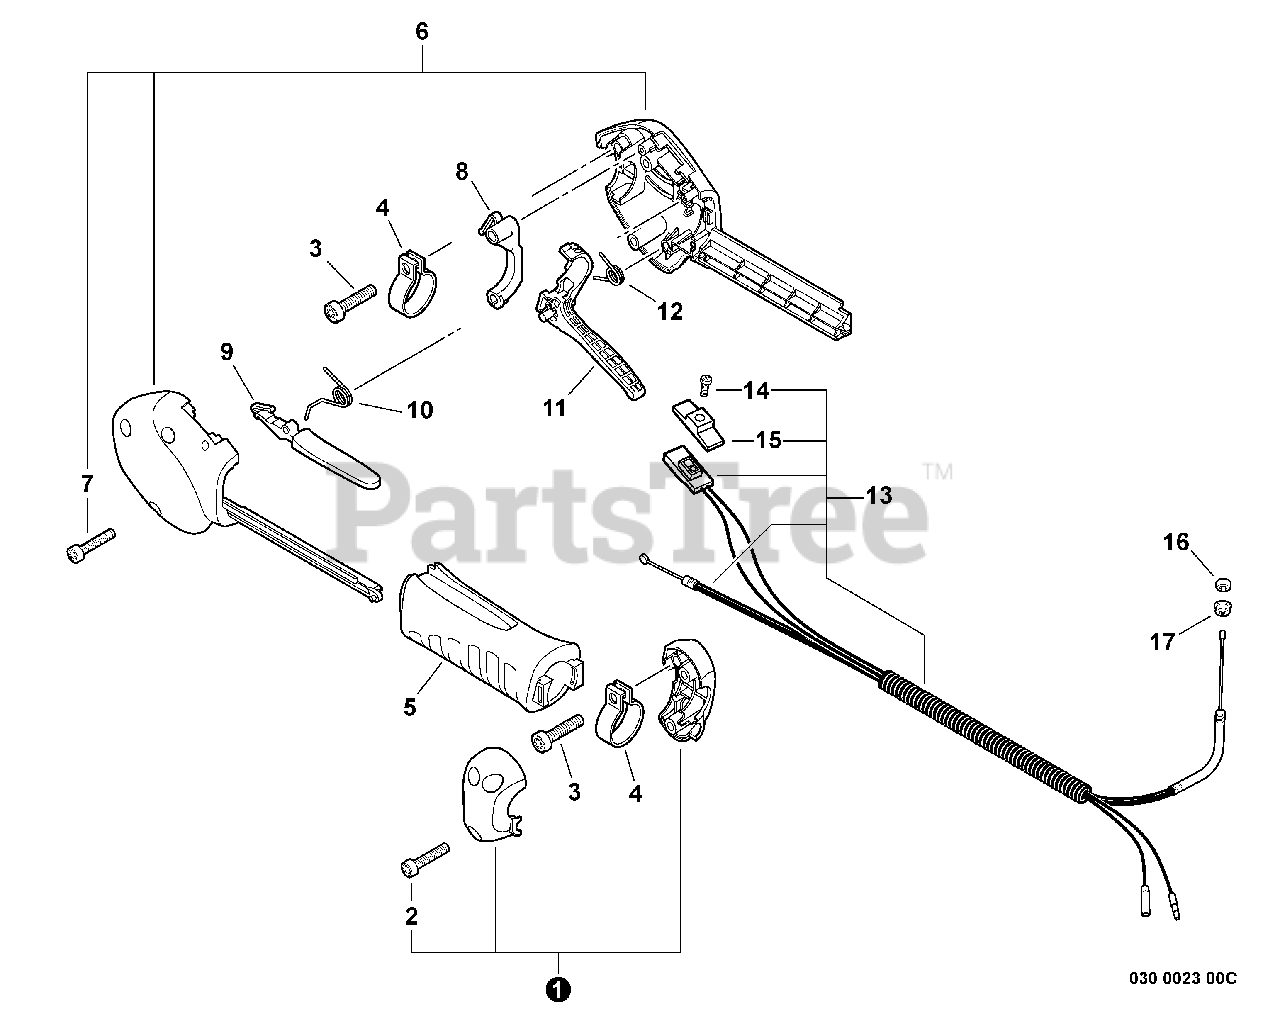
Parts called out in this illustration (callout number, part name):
1	GASKET KIT: ENGINE, INTAKE, EXHAUST
2	GASKET, CRANKCASE
3	GASKET, CYLINDER
4	GASKET, INTAKE
5	HEAT SHIELD, INTAKE
6	HEAT SHIELD, EXHAUST
7	GASKET, EXHAUST
8	FUEL SYSTEM KIT
9	VENT ASSY
10	FILTER, FUEL
11	GROMMET, FUEL Ø5
12	CONNECTOR, PIPE Ø5ר3.5
13	PIPE, FUEL 3×5×110 BLACK
14	PIPE, FUEL 3×6×80 CLEAR
15	PIPE, FUEL 3×5×74 BLACK
16	PIPE, FUEL 3×5×90 BLACK
17	CLIP Ø6
18	TUNE-UP KIT - REPOWER
19	FILTER, FUEL
20	FILTER, AIR - DOUBLE LAYER
21	SPARK PLUG - BPMR8Y
22	BULK STARTER ROPE - Ø 3.0 MM×61 M
23	BULK PIPE - 3×5 MM BLACK (4 PIECES×2 M)
24	BULK PIPE - 3×6 MM CLEAR (4 PIECES×2 M)
25	CAP/VENT KIT - REPOWER
26	CAP, FUEL
27	VENT ASSY
28	GASKET, FUEL CAP
29	FILTER KIT - REPOWER
30	FILTER, AIR - DOUBLE LAYER
31	FILTER, FUEL
32	FUEL SYSTEM KIT
33	GASKET, FUEL CAP
34	VENT ASSY
35	FILTER, FUEL
36	GROMMET, FUEL Ø5
37	PIPE, FUEL 3×6×80 CLEAR
38	PIPE, FUEL 3×5×90 BLACK
39	CLIP Ø6
